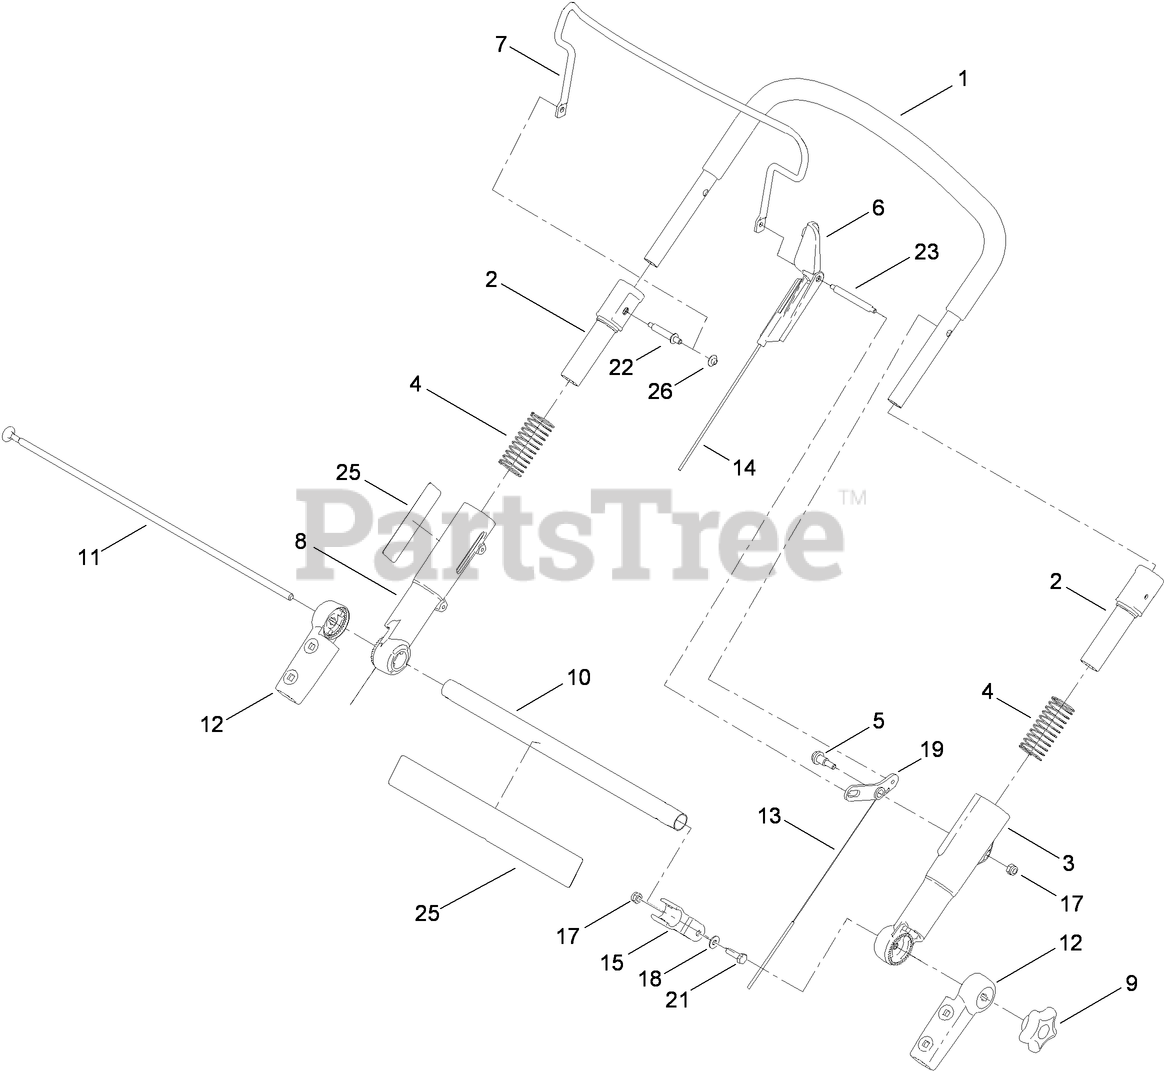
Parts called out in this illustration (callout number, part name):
1	UPPER HANDLE ASM
2	SLEEVE-INNER
3	SLEEVE-OUTER, LH
4	SPRING-COMPRESSION
5	BOLT-SHOULDER
6	STOP-PIVOT
7	BAIL-BRAKE
8	SLEEVE-OUTER, RH
9	KNOB-HANDLE
10	TUBE-CROSS
11	ROD-THREADED
12	MOUNT-HANDLE, LOWER
13	CABLE-TRACTION
14	CABLE-BRAKE
15	CLAMP-CABLE
17	NUT-LOCK, NI
18	WASHER-FLAT
19	LEVER-TRACTION
21	SCREW-HH
22	PIN-HANDLE
23	PIN-BAIL, LH
25	DECAL-ADS
26	RETAINER-PUSH ON
